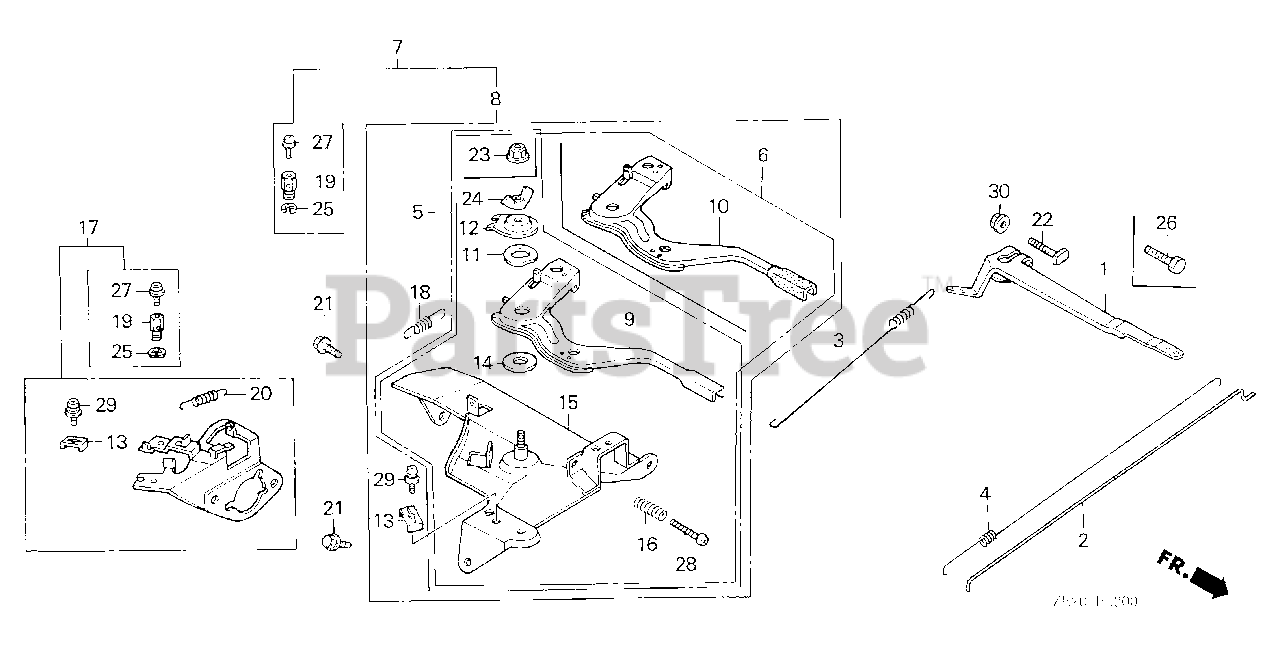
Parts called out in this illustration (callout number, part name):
1	ARM, GOVERNOR
2	ROD, GOVERNOR
3	SPRING, GOVERNOR (L=145.0MM) (WIRE DIAMETER 1.0MM)
4	SPRING, THROTTLE RETURN
8	CONTROL ASSY. (REMOTE)
9	LEVER, CONTROL
11	SPRING, LEVER
12	WASHER, CONTROL LEVER
13	HOLDER, CABLE
14	SPACER, CONTROL LEVER
15	BASE, CONTROL
16	SPRING, CONTROL ADJUSTING
18	SPRING, CABLE RETURN
21	BOLT, FLANGE (6X12) (CT200)
22	BOLT, GOVERNOR ARM
23	NUT, SELF-LOCK (6MM)
24	WINGNUT (6MM)
26	BOLT, HEX. (6X22)
28	SCREW, PAN (5X28)
29	SCREW, PAN (5X16)
29	SCREW-WASHER (5X16)
30	NUT, FLANGE (6MM)
